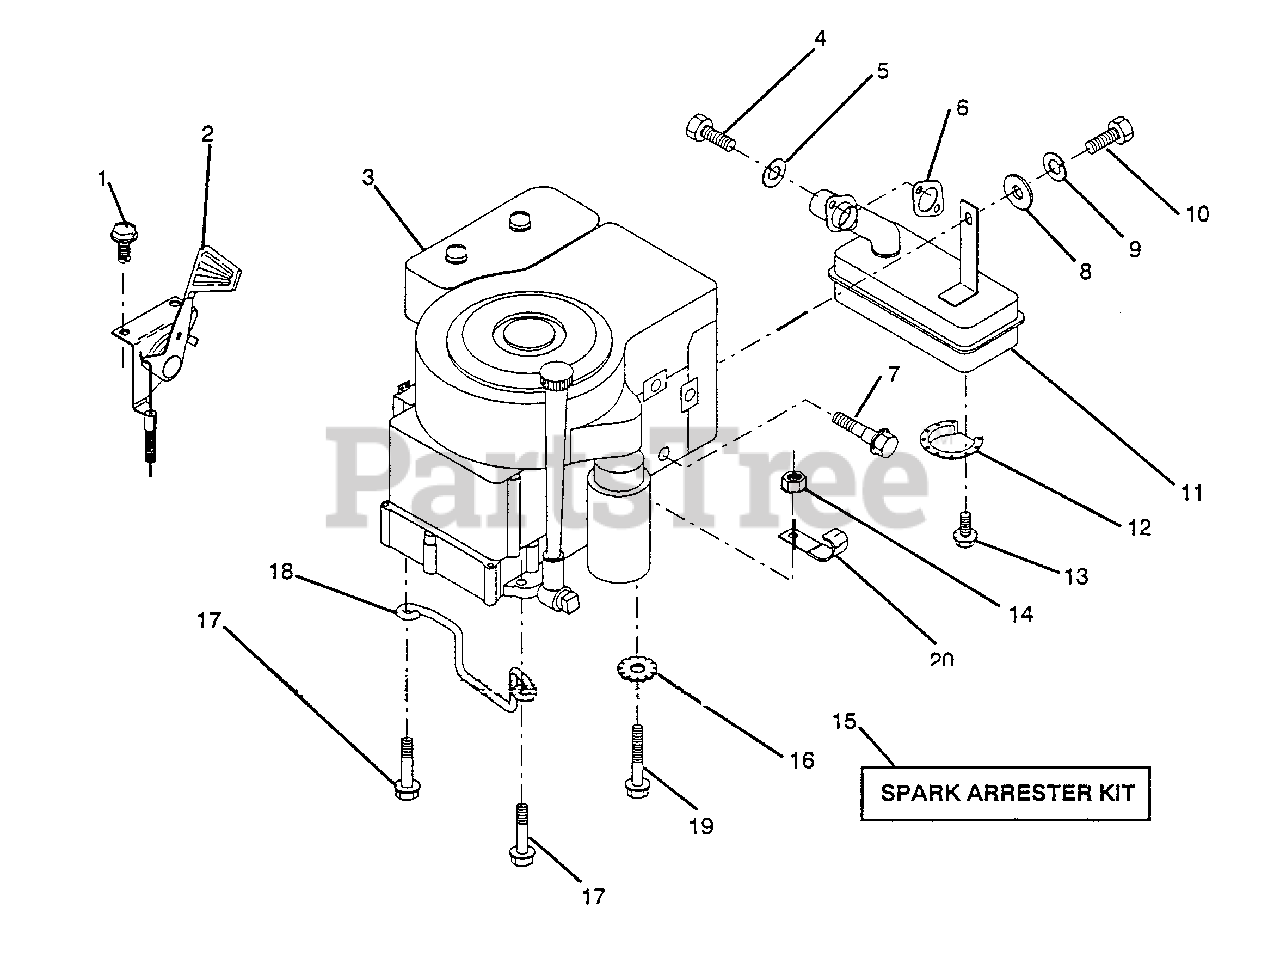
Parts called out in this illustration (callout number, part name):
1	Screw, Hex Thd. Cut 1/4-20 x 1/2
2	Control, Throttle
3	Engine, Briggs and Stratton Model No. 281707 Type No. 0122-01
4	Screw, Hex, Cap 5/16 -18 x 3/4
5	Washer, Lock Heavy Helical Spring 5/16
6	Gasket, Exhaust
7	Bolt, Shoulder 5/16
8	Washer, 5/16 x 3/4 x 16 Ga.
9	Washer, Lock Heavy Helical Spring 1/4
10	Bolt, Hex Fin. 1/4-20 UNC x 1-1/2
11	Muffler
12	Deflector, Muffler
13	Screw, Spiderlock Hex Hd. 8 x 1/2 ABTPS
14	Nut, Keps 3/8-16
15	Arrester, Spark
16	Lock Washer, Ext. Tooth 3/8
17	Screw, Hex Wsh Hd Thdrol 3/8-16 x 1 1/2
18	Keeper, Ground Drive Belt
19	Screw, Hex Wsh Hd Thdrol 3/8 - 16 x 2
20	Clip, Fuel Line
